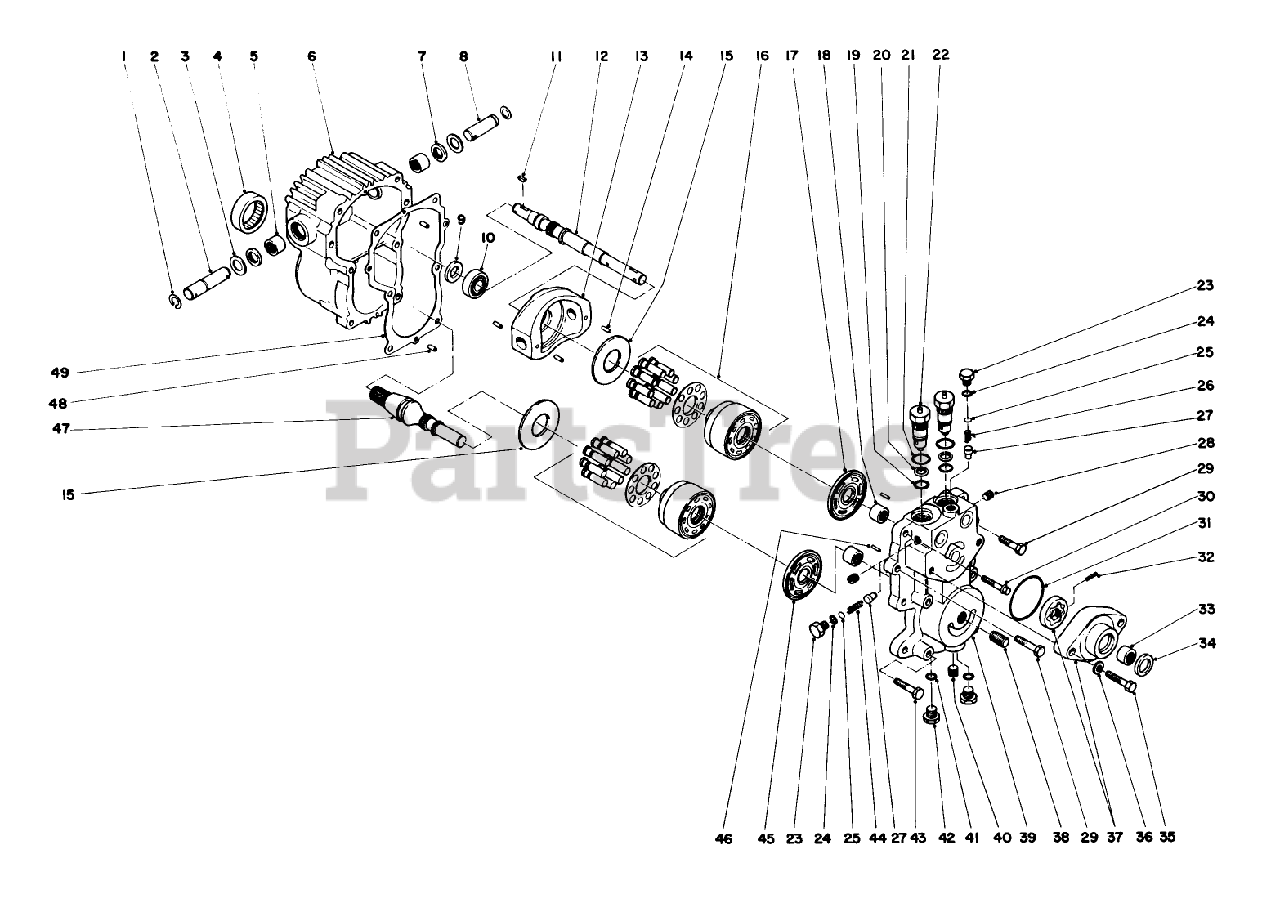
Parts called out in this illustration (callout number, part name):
1	RING-RETAINING
2	SHAFT-TRUNNION
3	WASHER-FLAT
4	BEARING-ROLLER
5	Bearing-Needle
6	Housing
7	SEAL-LIP
8	SHAFT-TRUNNION
9	Up Seal
10	BEARING-BALL
11	KEY-WOODRUFF
12	SHAFT-PUMP
13	Swashplate-Variable
14	PIN-SPRING
15	Thrust Plate
16	CYLINDER BLOCK KIT
17	PLATE-VALVE, PUMP
18	BEARING-NEEDLE
19	O-RING
20	RING-BACK UP
21	O-RING
22	Check Valve Assembly (Incl. Ref. #19-21)
23	PLUG-HH
24	O-RING
25	Shim Pack
26	SPRING
27	Cone-Charge Relief
28	PLUG-PIPE
29	SCREW-HH
30	CAPSCREW
31	O-RING
33	BEARING
34	SEAL-LIP
35	SCREW-HH
36	WASHER
37	Charge Pump Kit (Incl. Ref. #31-34)
38	UNION-FILTER
39	CENTER SECTION
40	PIPE PLUG
41	"O" Ring
42	Threaded Plug (Incl. Ref. #41)
43	SCREW-HH
44	SPRING-VALVE
45	PLATE-VALVE, MOTOR
46	PIN-DOWEL
47	SHAFT-MOTOR
48	Pin
49	GASKET
